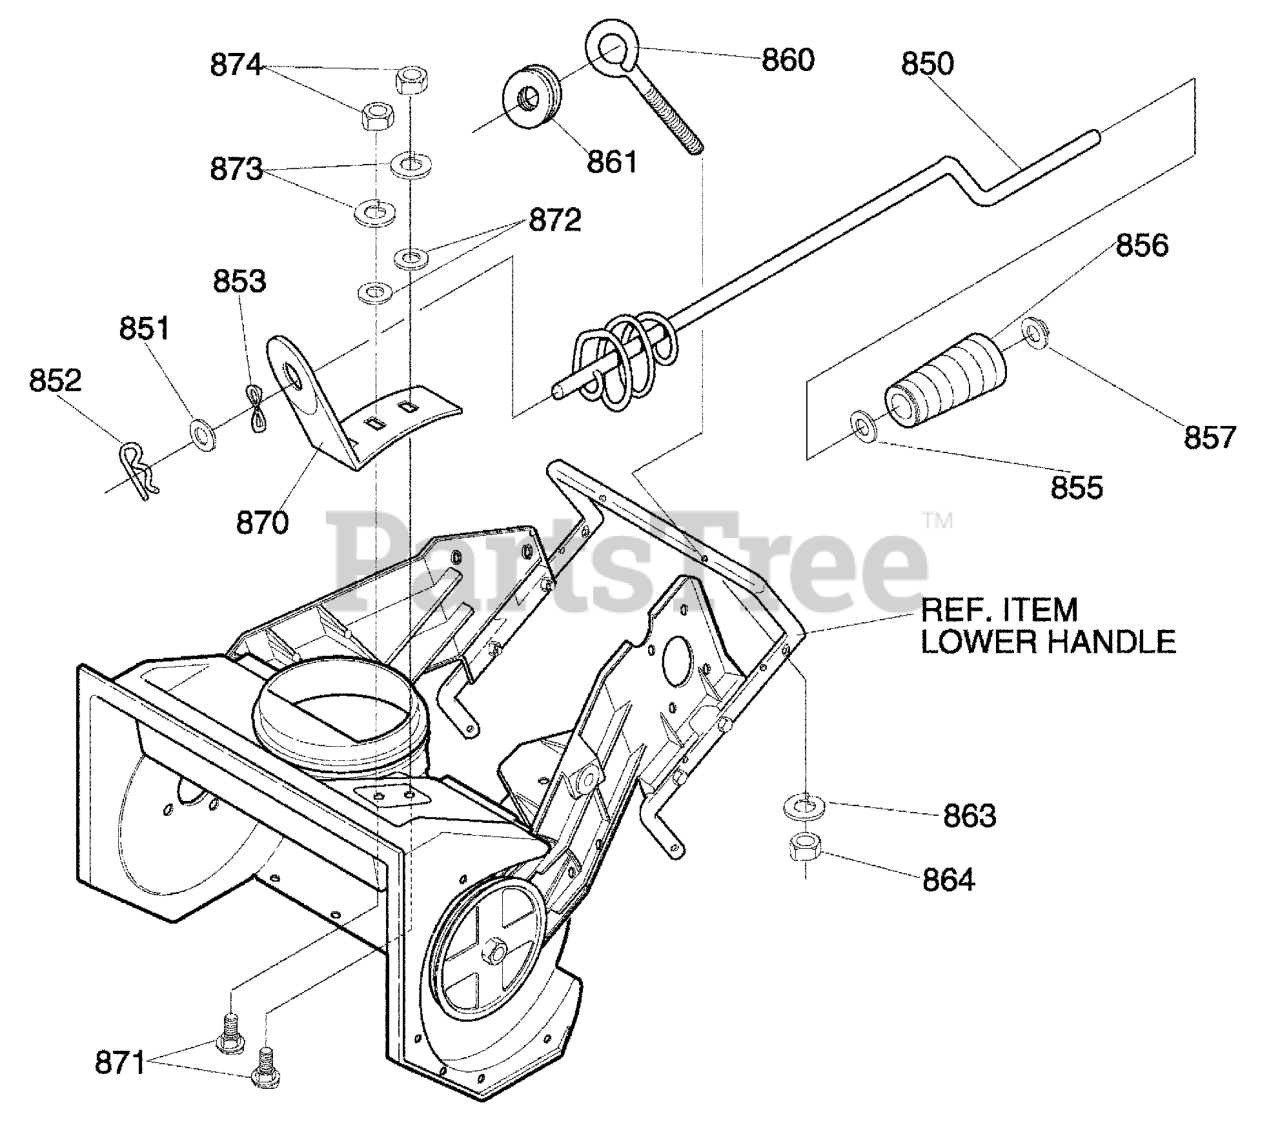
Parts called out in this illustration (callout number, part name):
850	ROD, ASSY UPPER CHUTE CONTROL
851	WASHER, FLAT
852	PIN, COTTER
853	WASHER, CURVED SPRING
855	WASHER, FLAT
856	KNOB, SLEEVE
857	NUT, PUSH
860	BOLT, EYE 3/8-16X2.00
861	GROMMET, EYE BOLT
863	WASHER, MDSPTLK
864	NUT, 3/8-16 HEXJAM
870	BRACKET, CHUTE ROTATE
871	BOLT, CARRIAGE
872	WASHER, FLAT
873	WASHER
874	NUT, 5/16-18
